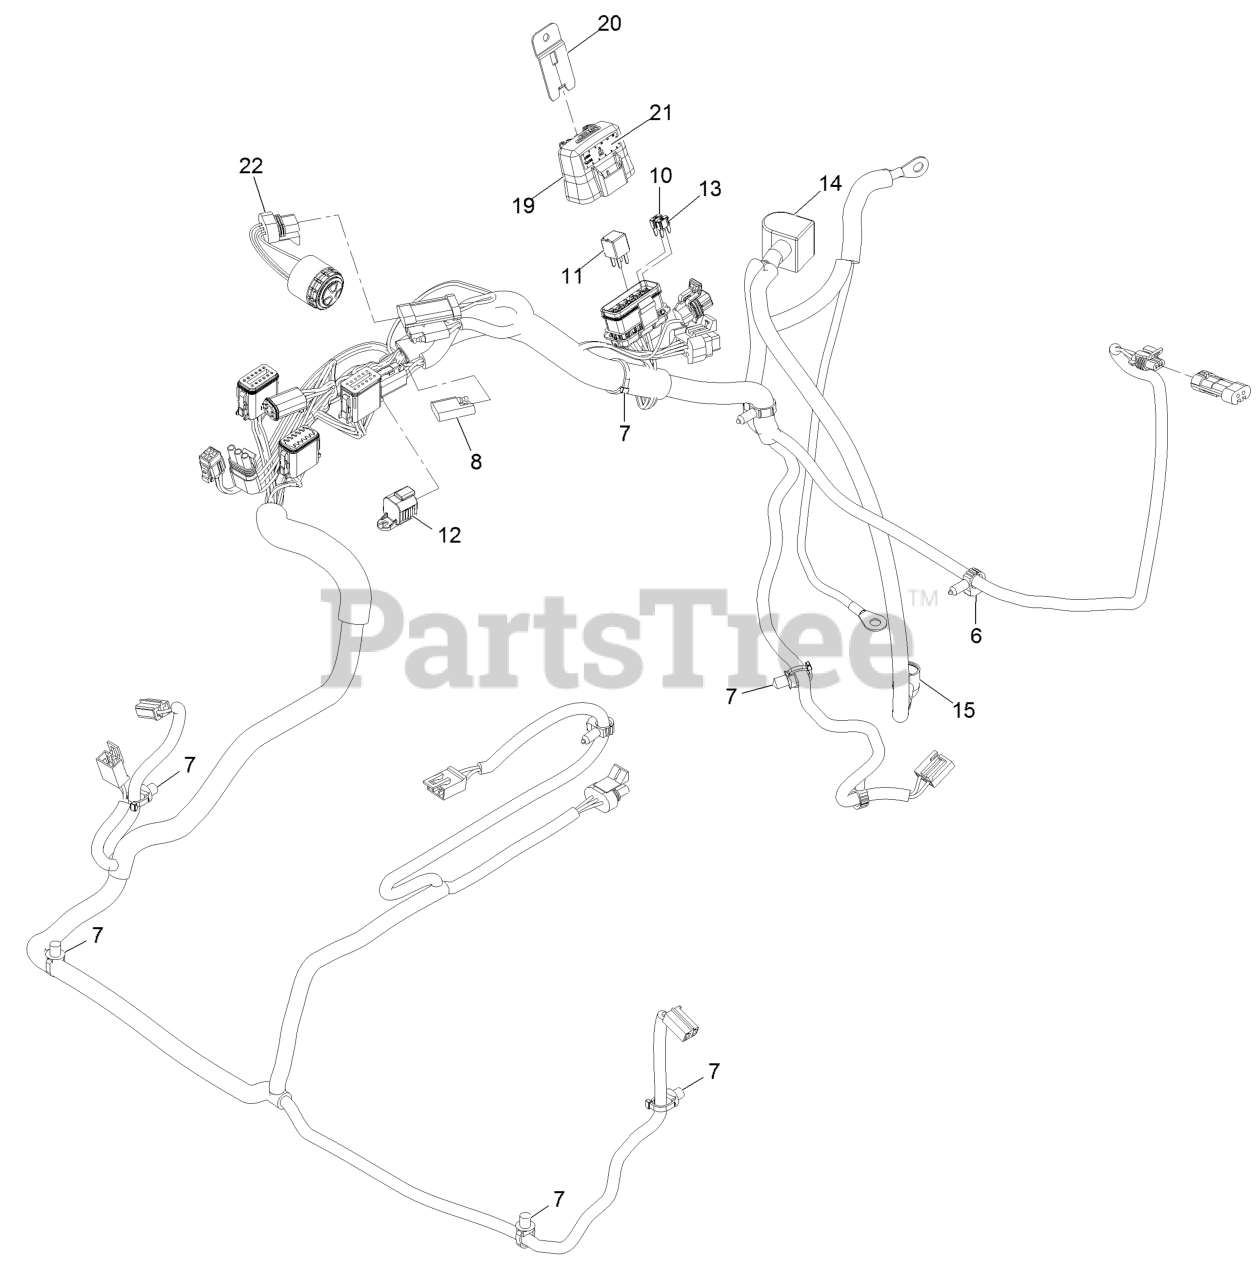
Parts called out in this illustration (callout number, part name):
6	Clip-Harness
7	Clip-Tie
8	Cap-Plug, SAE J928-32, Molded
10	Fuse-Mini Blade, 20 Amp
11	Relay-Micro
12	Cap-Plug, 6 Way
13	Fuse-Mini Blade, 15 Amp
14	Insulator-Battery
15	Insulator-Solenoid
19	Cover-Block, Fuse
20	Clip-Mounting
21	Decal-Fuse
22	Alarm-Dual Tone
